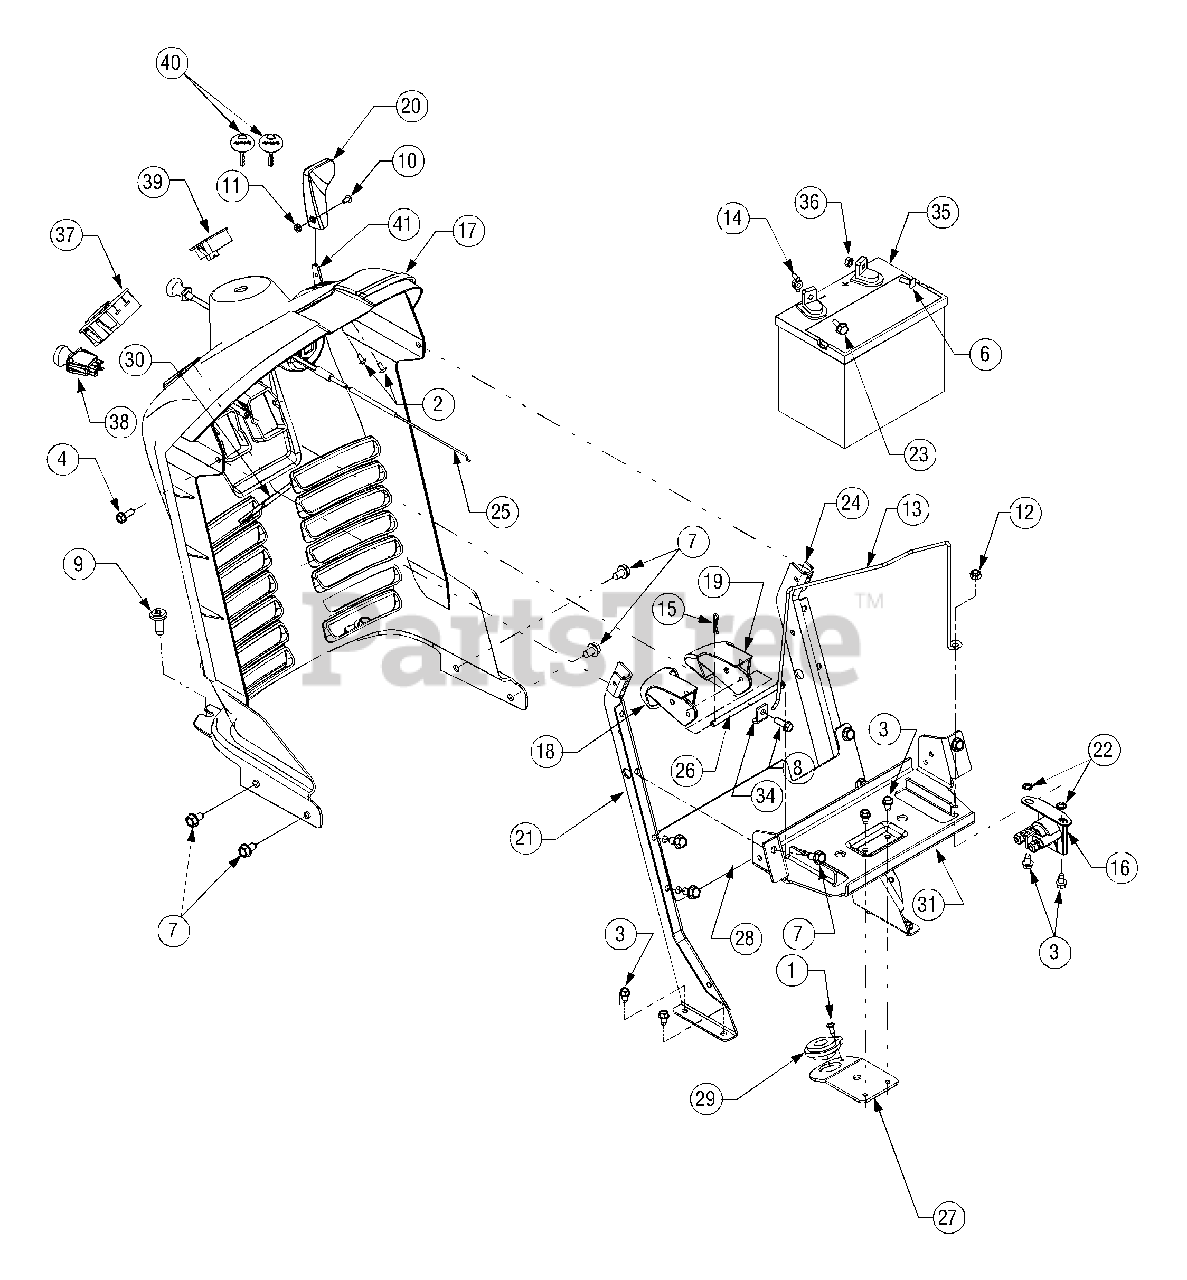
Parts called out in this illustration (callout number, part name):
1	Screw, #10-16 x .625
2	Screw, #10-24 x .375
3	Screw, Self-tapping, 1/4-20, 0.500
4	Screw, Hex. 1/4-20 x .75
5	Screw, Hex, 5/16-18, .875 Gr5
6	Screw, Carriage, 1/4-20, .75,
7	Screw, Hex, 5/16-12 x .75
8	Screw, 1/4-15, 0.750
9	Screw, Torx Hd. Tapp. 5/16-18 x .75
10	Screw, Machine, #8-32, 0.375, Trus Phillips
11	Nut, 8-32
12	Nut, Nylon Lock, 1/4-20
14	Nut, Wing, 1/4-20
15	Internal Cotter Pin, .072 x 1.13
16	Solenoid, 12V, 100 Amp
17	Dash
18	Lever, Dash, Cruise
19	Lever, Dash, Brake
20	Knob, Throttle Control
23	Screw, Shoulder, 1/4-20, .25 x .15
25	Control, Choke, 24.0 (LT1042 & LT1045)
26	Rod, .250 Dia x 4.25 Lg.
30	Bracket, PTO Switch Retainer
35	Battery, 190 CCA (LT1042 & LT1045)
36	Nut, Sems, 1/4-20
37	Switch Module, Ignition
38	Switch, PTO, Yellow (LT1042 & LT1045)
39	Monitor, Systems Indicator / Hour Meter
40	Ignition Key, Plastic
41	Control, Throttle, 27.4 (LT1042 & LT1045)
